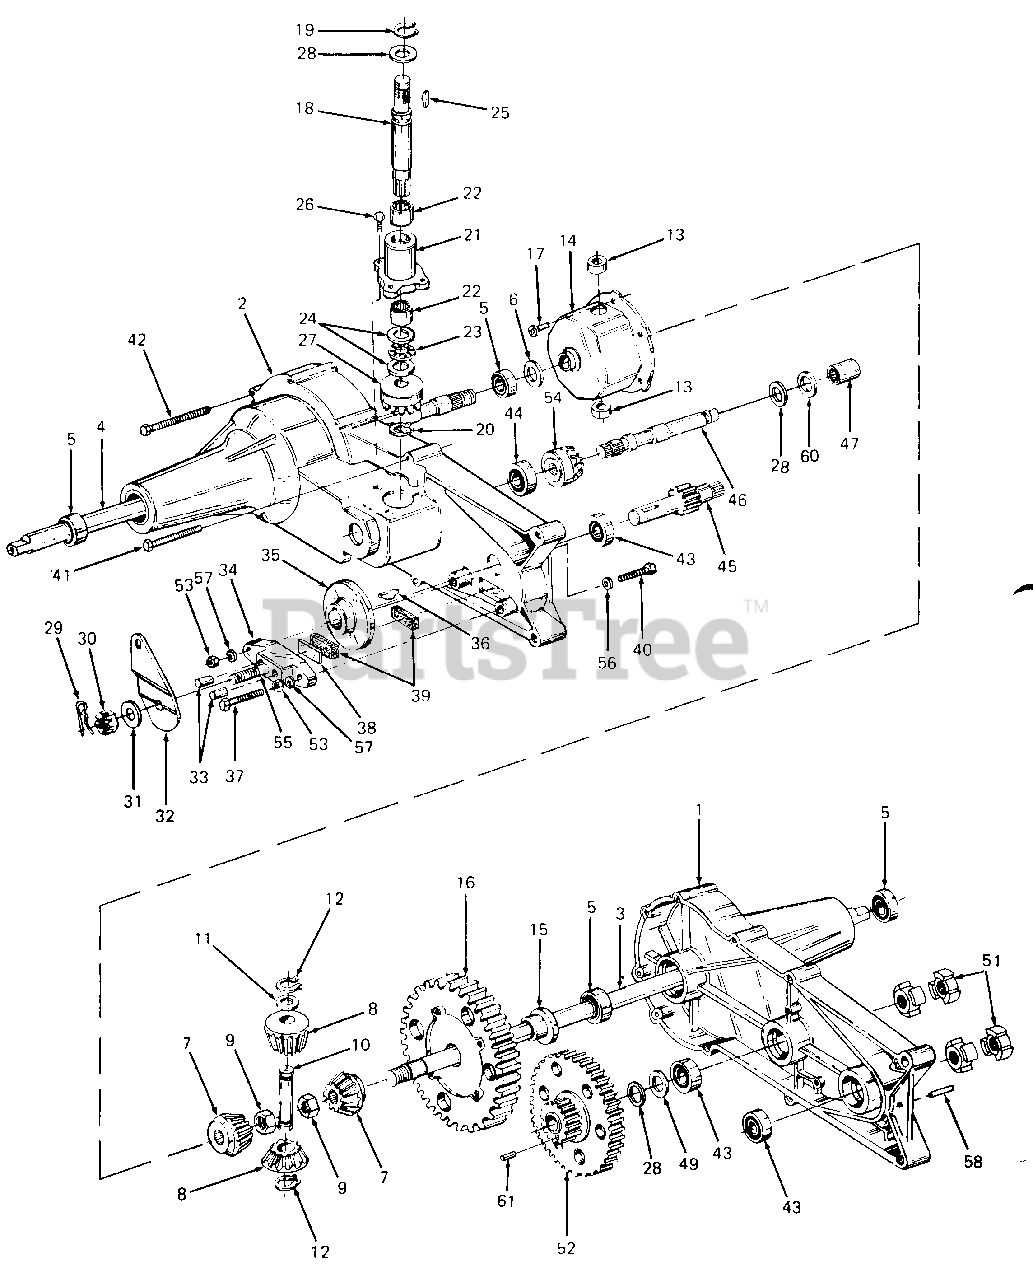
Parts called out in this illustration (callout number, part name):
1	Housing Half, L.H.
2	Housing Half, R.H.
3	Axle, L.H.
4	Axle R.H.
5	Bearing, Ball
6	Washer, Flat, .76 x 1-1/8" x .306 Thk. Hdn.
7	Gear, Miter
8	Gear, Miter
9	Nut, Hex Jam Patch Lock, 1/2-20
10	Shaft, Cross
11	Washer, Flat, .505 I.D. x 1.0
12	Ring, Snap
13	Bearing, Thrust
14	Housing Ass'y. Differential
15	Bearing, Flange, .75 I.D. x .587
16	Gear, Differential, 72 Tooth
17	Screw, Pan Hd. Patch Lock 1/4-20 x .50 Lg.
18	Shaft, Input
19	Ring, Snap
20	Ring, Retaining, Ext. 7/16 Dia.
21	Bearing, Input Housing
22	Bearing, Needle, 5/8 I.D. x .50 Lg.
23	Bearing, Thrust
24	Washer, Flat, 5/8 I.D. x 1.12 O.D. x .030 Thk.
25	Key #4 Hi-Pro, 3/32 x 5/8 Dia. (Hdn .)
26	Screw, Hex Patch Lock, 1/4-20 x 3/4 Lg.
27	Gear, Input Pinion, 17 Tooth
28	Washer, Flat, .62 I.D. x 1.0 O.D. x .030 Thk.
29	Pin, Cotter
30	Nut, Castle, 5/16-24
31	Washer, Flat, .343 x .88 x .062 Thk.
32	Arm, Brake Actuator
33	Pin, Actuating, 5/16 Dia.
34	Yoke, Brake
35	Disc, Brake
36	Key, Hi-Pro, 3/16 x 5/8 Dia.
37	Screw, Hex Patch Lock, 1/4-20 x 1.5 Lg.
38	Plate, Puck
39	Puck, Brake
40	Screw, Hex Cap, 1/4-20 x 1.5 Lg.
41	Screw, Hex Self-Tap, 1/4-20 x 2.0 Lg.
42	Screw, Hex Self-Tap, 1/4-20 x 2.75 Lg.
43	Bearing, Ball
44	Bearing, Ball
45	Shaft, Pinion w/11 Tooth Gear
46	Shaft, Drive
47	Bearing, Needle
49	Washer, Flat, 5/8 x 1.12 x .060 Thk.
51	Coupling
52	Gear, Tooth 60 & 17
53	Nut, Hex Jam, 1/4-20
54	Gear, Drive Pinion, 17 Tooth
55	Bolt, Square Hd. 5/16-24
56	Washer, Flat, .265 x .938 x .12 Thk.
57	Washer, Lock, 1/4
58	Pin, Roll, 3/16 Dia. x .50 Lg.
60	Bronze Thrust Brg. 518" I.D.
61	Dowel Pin 3/32" x 1/4"
